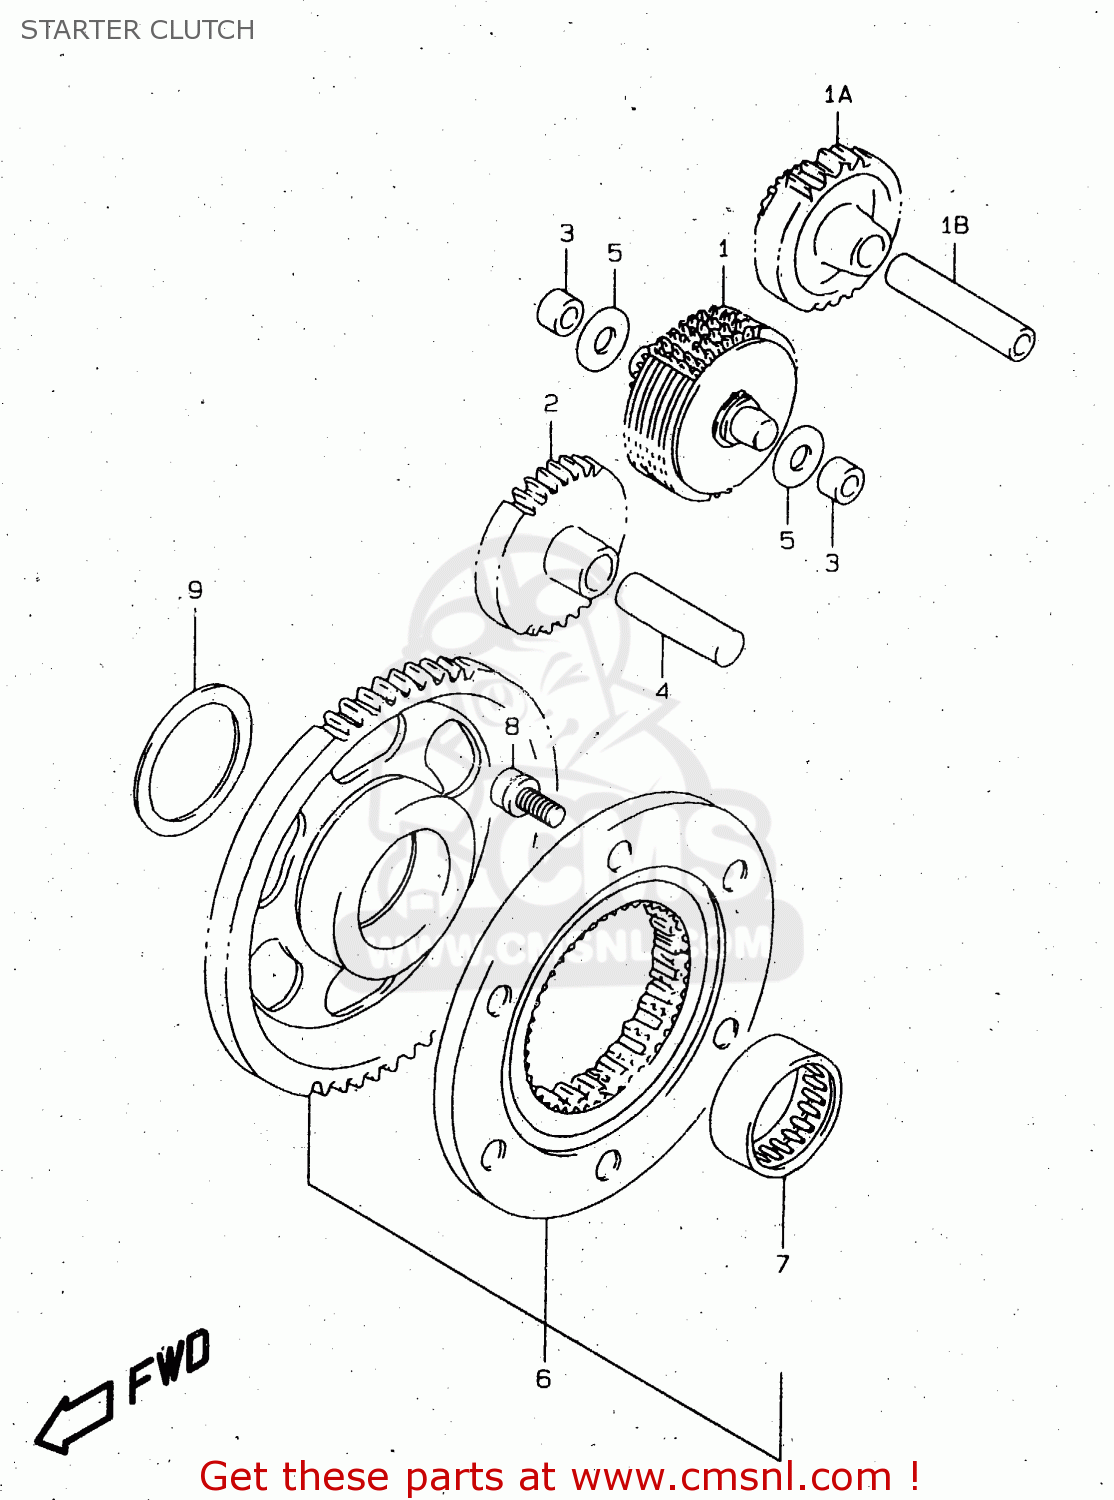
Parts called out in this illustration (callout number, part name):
1	LIMITER ASSEMBLY,STARTER IDLER GEAR
1A	GEAR,STARTER IDLE NO.1
1B	PIN(8X12X59)
2	GEAR,STARTER IDLE NO.2(NT:27)
3	BUSH,LIMITER GEAR SHAFT
4	PIN
5	WASHER
6	CLUTCH SET,STARTER
7	BEARING(31X39X17.8)
8	BOLT
9	SHIM
